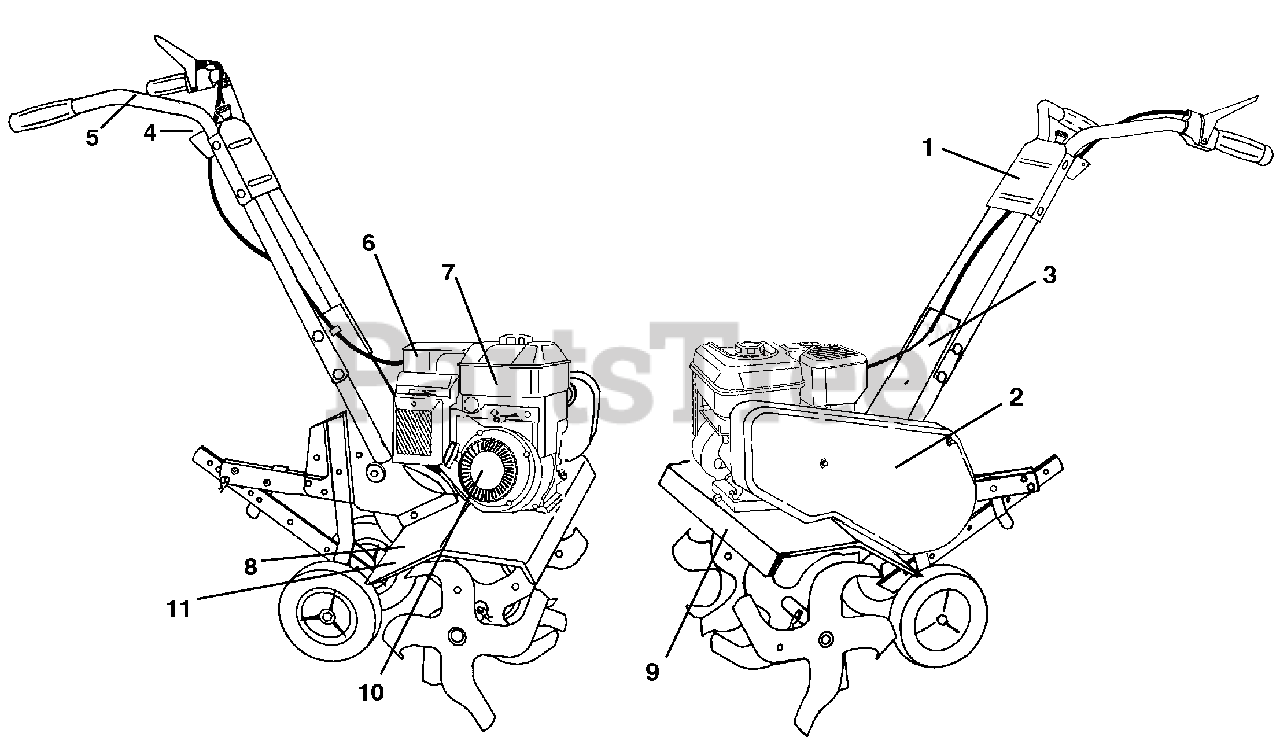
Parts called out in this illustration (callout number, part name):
1	Decal, Poulan Pro
2	Decal, Poulan Pro, 825 Series / 26"
3	Decal, Forward and Reverse
4	Decal, Reverse, Tine Control
5	Decal, Hand Placement
6	Decal, Engine
7	Decal, OHV, I/C
8	Decal, Warning
9	Decal, Heavy Duty
10	Decal, Rewind Starter
11	Decal, Warning, Rotating Tines
11	Manual, Operator's, English / French
11	Manual, Repair Parts
